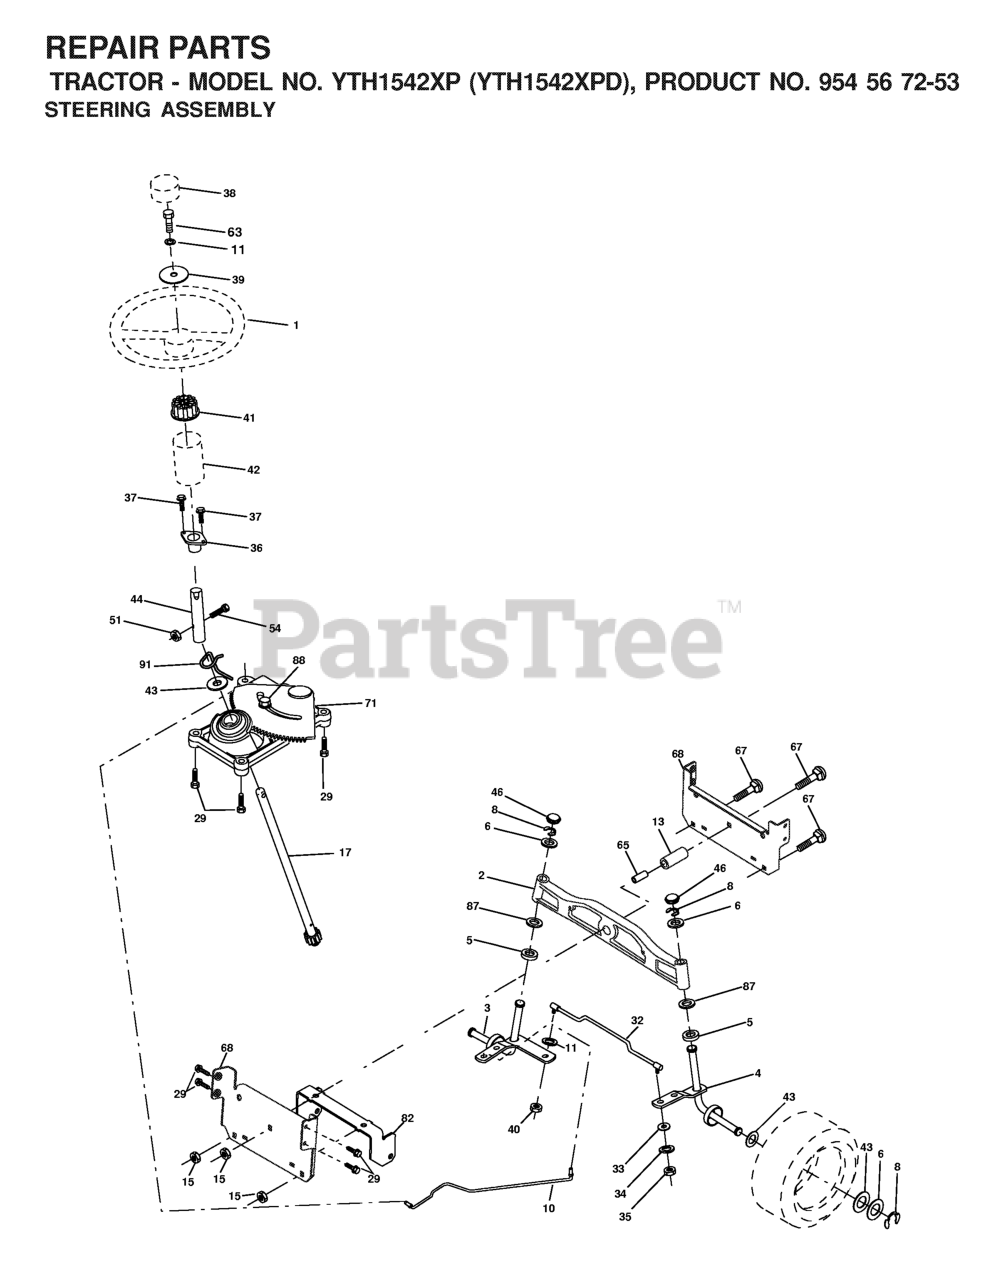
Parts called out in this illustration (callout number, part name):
1	STEERING WHEEL
2	AXLE ASM
3	SPINDLE.ASM.LH.15"TIRES
4	SPINDLE.ASM.RH.15"TIRES
5	THRUST WASHER
10	DRAGLINK.15".TIRES.2001
11	WASHER, LOCK 3/8
13	TUBE, PIVOT AXLE
15	NUT
17	SHAFT ASM
29	SCREW 3/8-16X3/4
33	WASHER M
34	WASHER.LOCK.HVY.HLCL.SPR.5/16
35	NUT, CROWNLOCK
36	BUSHING, STEERING
37	SCREW.TT.#10-32X.5.3/8.FLANGE
38	CAP.WHEEL.STEERING.GREY
39	Washer 13/32 x 1-1/20 x 11 Gauge
40	GRIPCO NUT
41	STEERING WHEEL ADAPTOR
42	BOOT STEERING
44	EXT SHAFT STEERING
46	CAP.SPINDLE.BLACK
51	NUT.71038.31-18.HEX.NYLOCK
54	BOLT.5/16-18X1-1/4 FULL.THREAD
65	SPACER BRACE AXLE
67	BOLT
68	BRACE.AXLE.15"TIRES
71	STEERING ASM
82	BRACKET
87	WASHER, FLAT .781 X 1 1/2"
88	BOLT, SHOULDER 7/16-20
91	CLIP.STEERING
